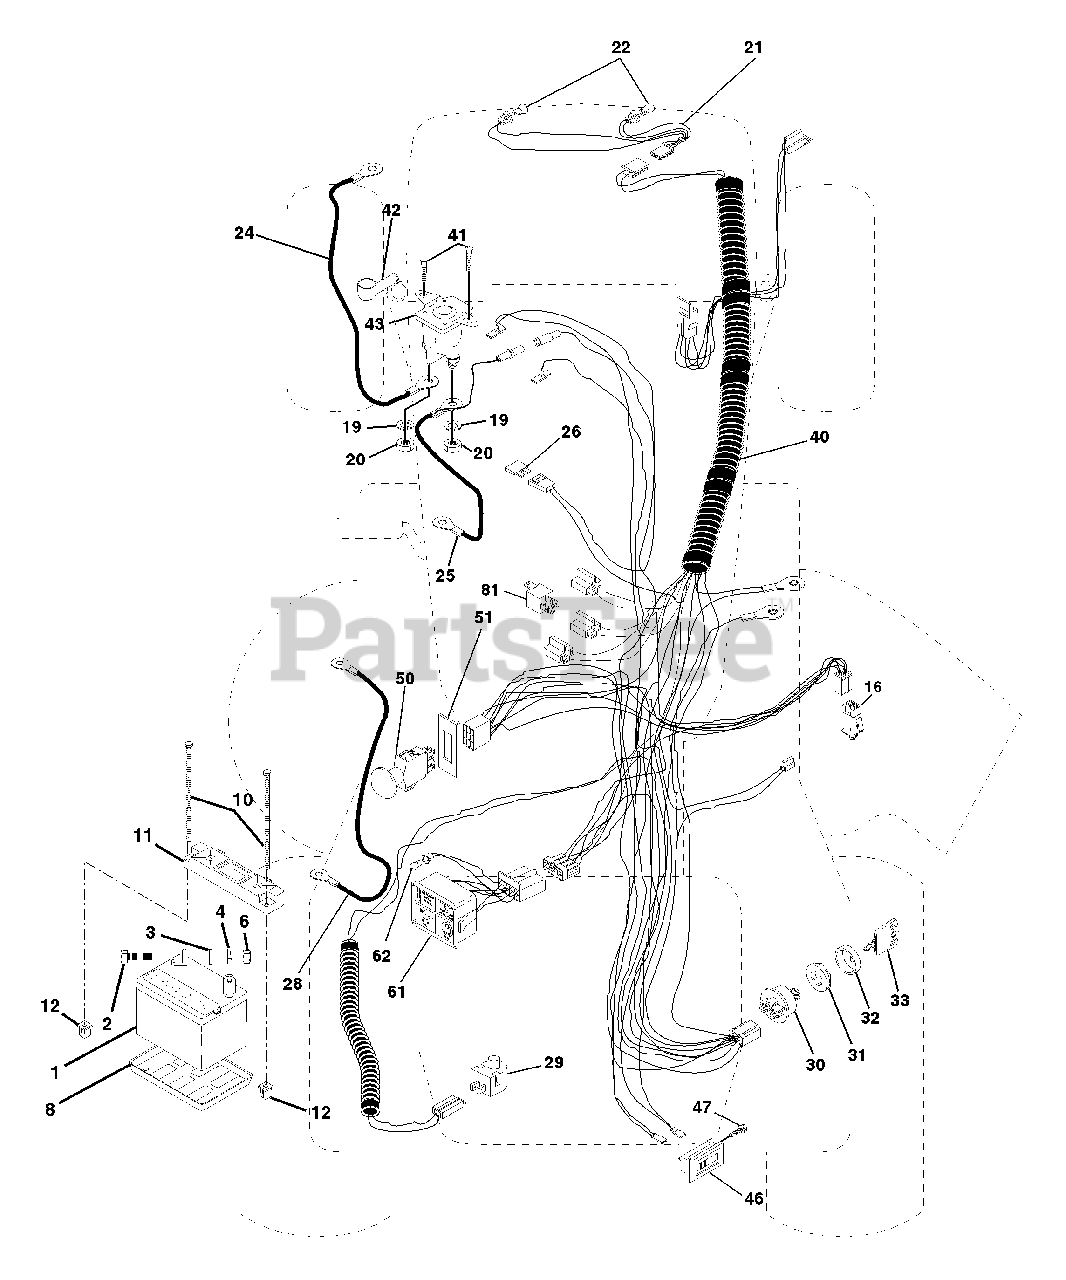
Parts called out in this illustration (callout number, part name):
1	Battery
2	Bolt Hex Head 1/4-20 x 3/4
3	Washer, Lock 1/4
4	Washer 9/32 x 5/8 x 16 Ga
6	Nut Fin Hex 1/4-20
8	Tray, Battery
10	Bolt, Btr Frt 1/4-20 x 7-1/2 Zinc
11	Holddown Battery Front Mount
12	Nut Push Nylon 1/4" Battery Frt.
16	Switch Interlock Push-In
19	Washer, Lock 1/4
20	Nut, Jam Hex 1/4-20
21	Harness Socket Light w/4152J
22	Bulb Light
24	Cable, Starter
25	Cable, Battery
28	Cable, Ground
29	Switch, Plunger
30	Switch, Ign
31	Nut, Ignition Switch
32	Cover Switch Key
40	Harness Ign.
41	Screw 1/4-20 x 1/2
42	Cover, Terminal Red
43	Solenoid
46	Meter Hour
47	Screw #10-24 x 1/2
50	Switch, PTO
51	Ring Retainer PTO
61	Light Pkg Asm
62	Bulb, Light Pkg.
81	Relay Asm.
